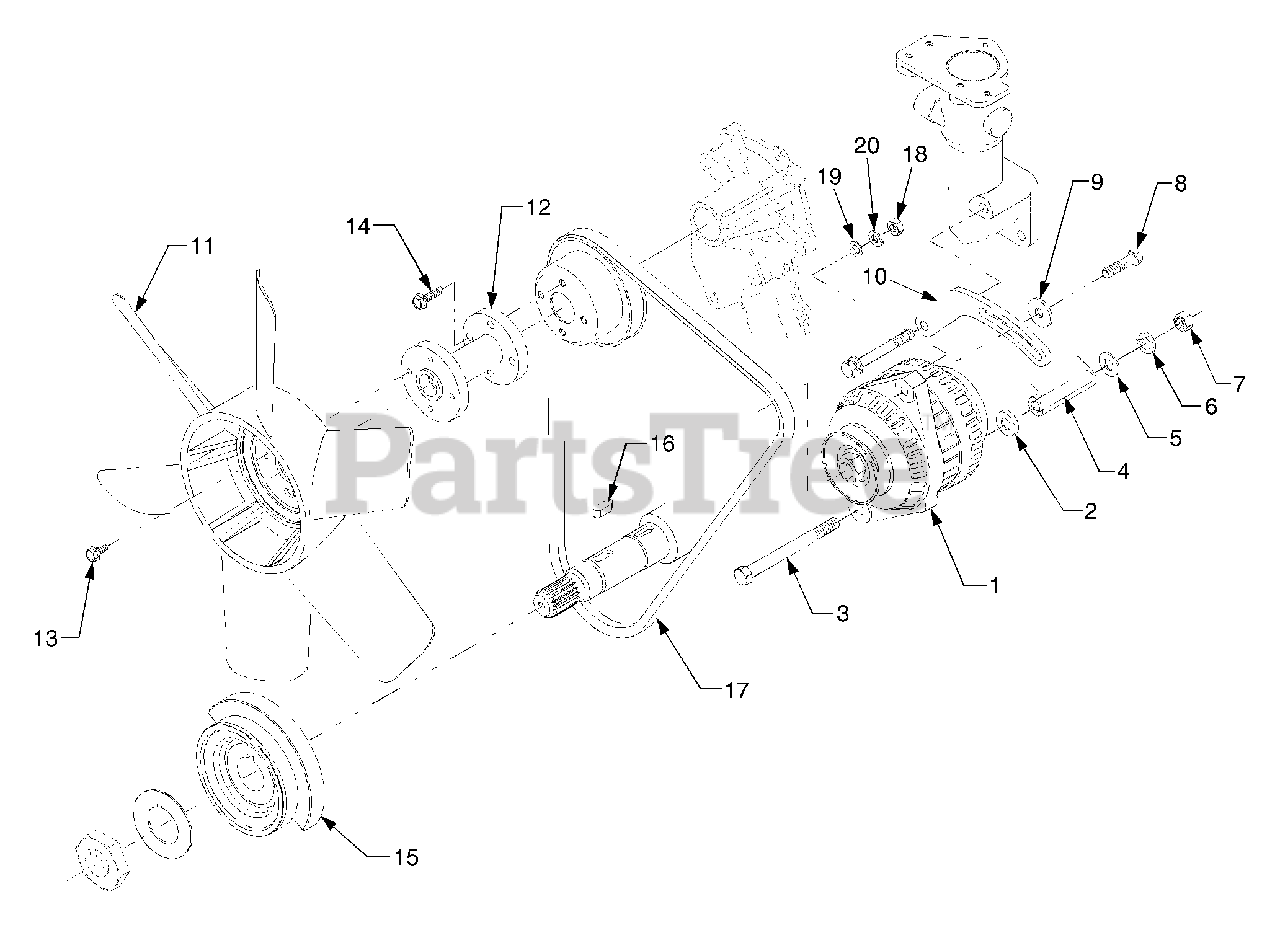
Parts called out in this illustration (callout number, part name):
1	Alternator Ass'y
5	Washer, Plain
6	Washer, Spring
9	Washer, Plain
10	Stay, Alternator
11	Fan, Coolling
15	Pulley, Fan Drive
19	Washer, Plain
20	Washer, Spring
